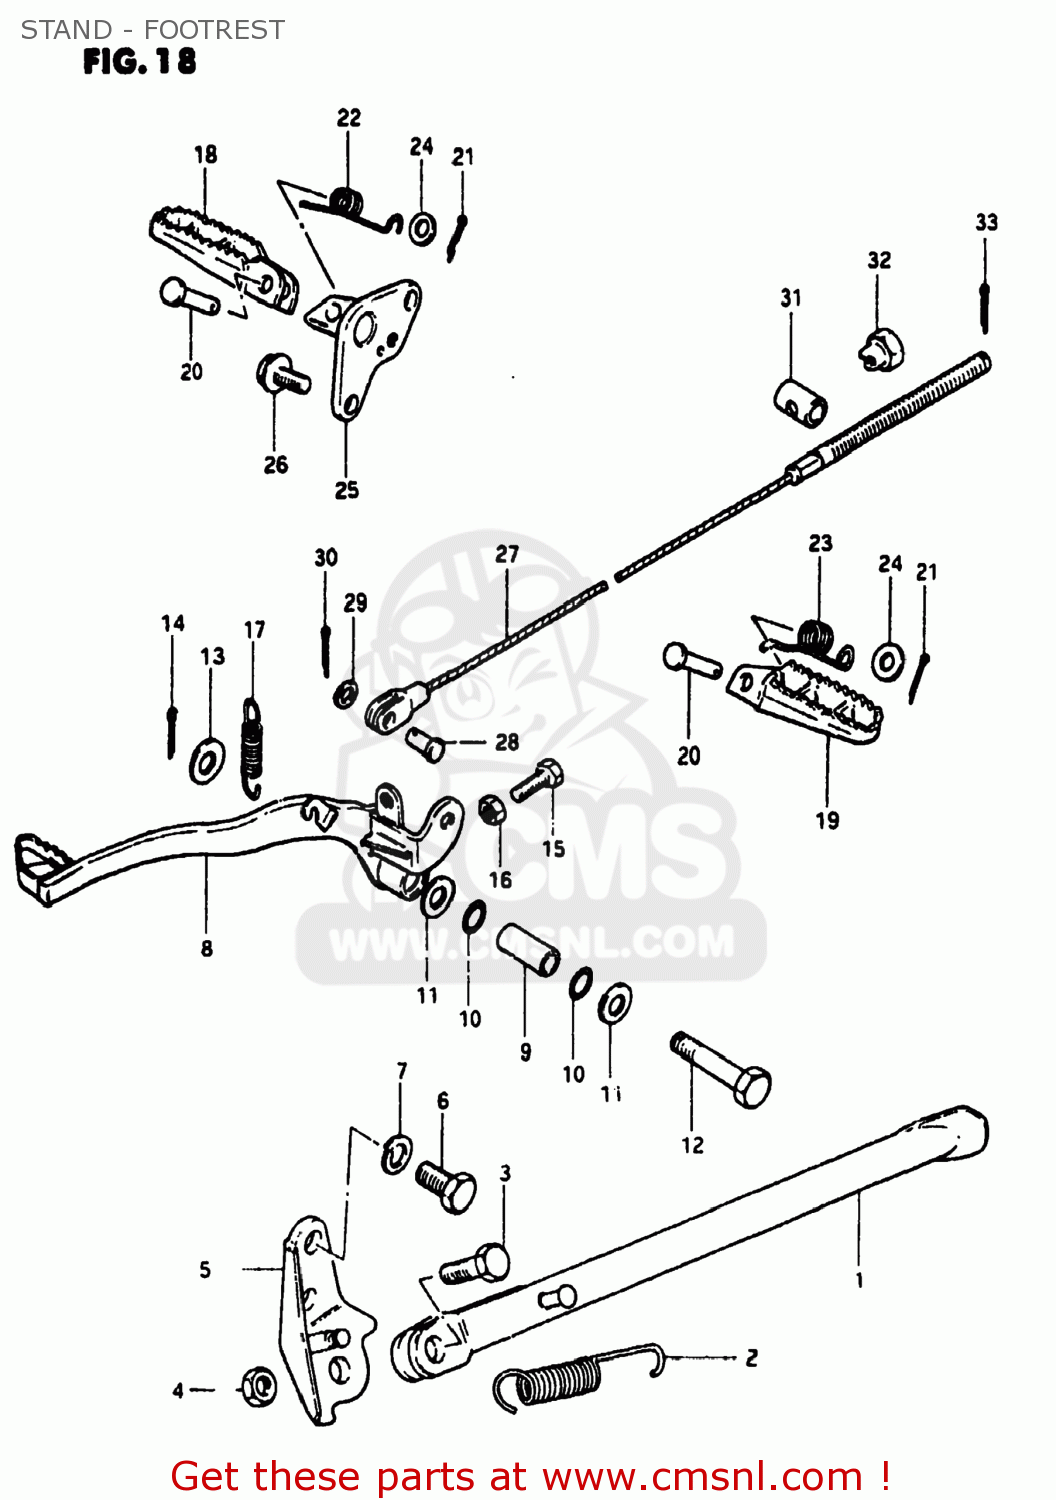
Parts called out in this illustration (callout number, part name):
1	STAND,SIDE
2	SPRING
3	BOLT(10X30)
4	NUT
5	BRACKET,PROP STAND
6	BOLT(10X19)
7	LOCK WASHER
8	PEDAL,BRAKE
9	SPACER (8X10X22)
10	O-RING (D:1.5 ID:10)
11	WASHER
12	BOLT 8X43.5
13	WASHER
14	PIN 20X20
15	BOLT 6X25
16	NUT
17	SPRING
18	RUBBER,FRONT FOOTREST
19	FOOTREST
20	PIN
21	PIN 20X20
22	SPRING
23	SPRING
24	WASHER
25	HOLDER,FRONT FOOTREST
26	BOLT(10X20)
27	CABLE ASSEMBLY,REAR BRAKE
28	PIN(L:17.5)
29	WASHER
30	PIN 20X20
31	PIN
32	NUT
33	PIN
